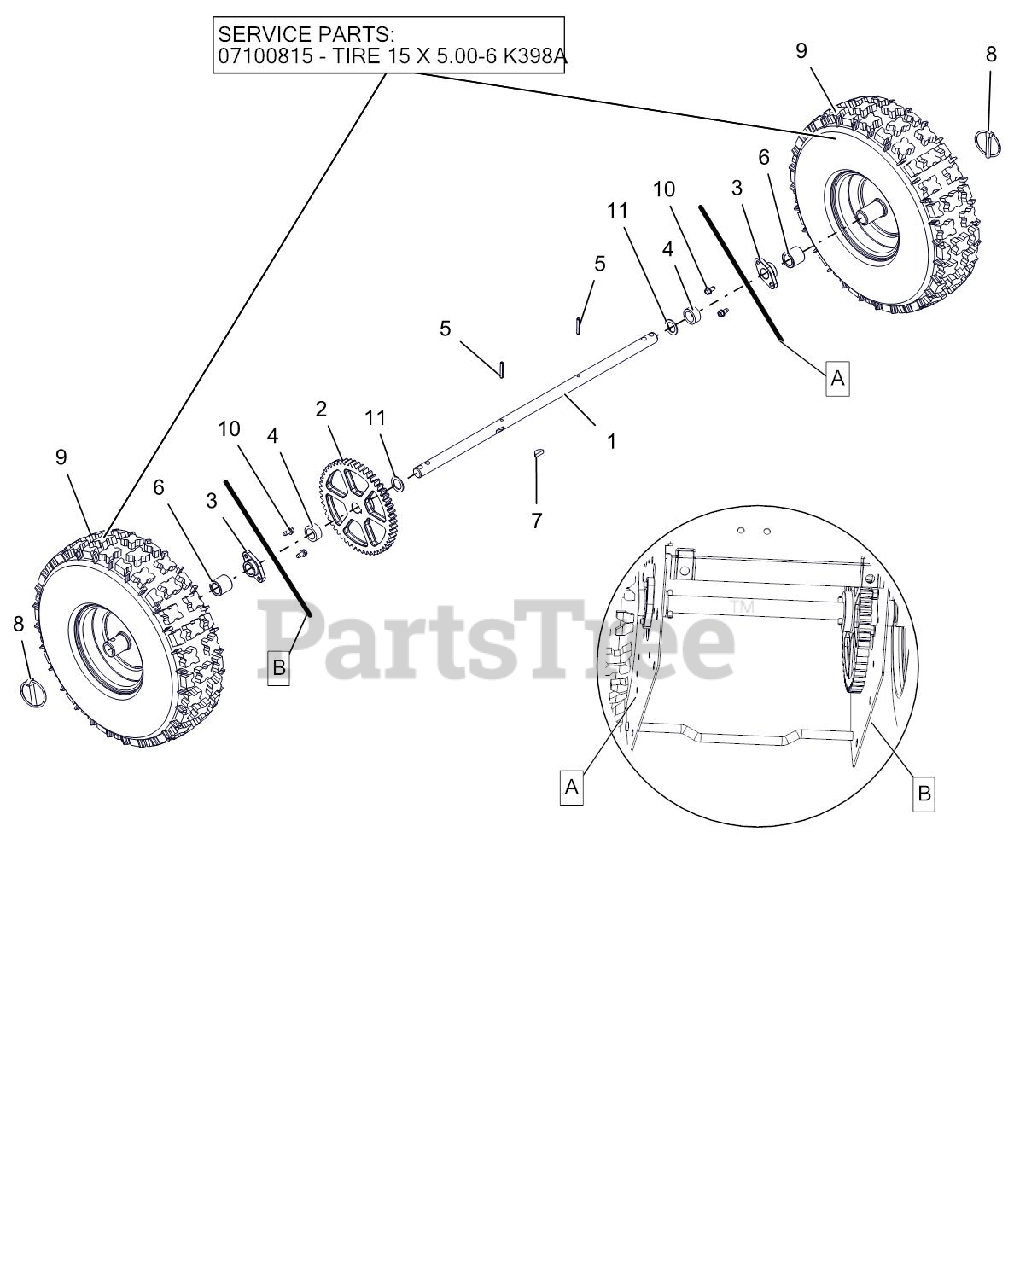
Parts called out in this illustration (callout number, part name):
1	AXLE, COMPACT 920,XXX 15" TIRE
2	SPUR GEAR, 54T .75ID X 6.75PD
3	BSHG .75X1.125X.65
4	BSHG-SLV .766 X 1.125 X .500
5	PIN-ROLL .188X1.25
6	BSHG-SLV .75X1.12X1.062 NYL BK
7	KEY-WDRF .25X.750X.313 SAE91
8	PIN-LOK .31X1.75
9	TIRE/WHEEL, 15X5.00-6 K398A
9	TIRE, 15" K398A
10	SCR-TAP .25-20X.50 HWH TR YWZ
11	WSHR-FL-STL.754X1.125X.062YWZC
